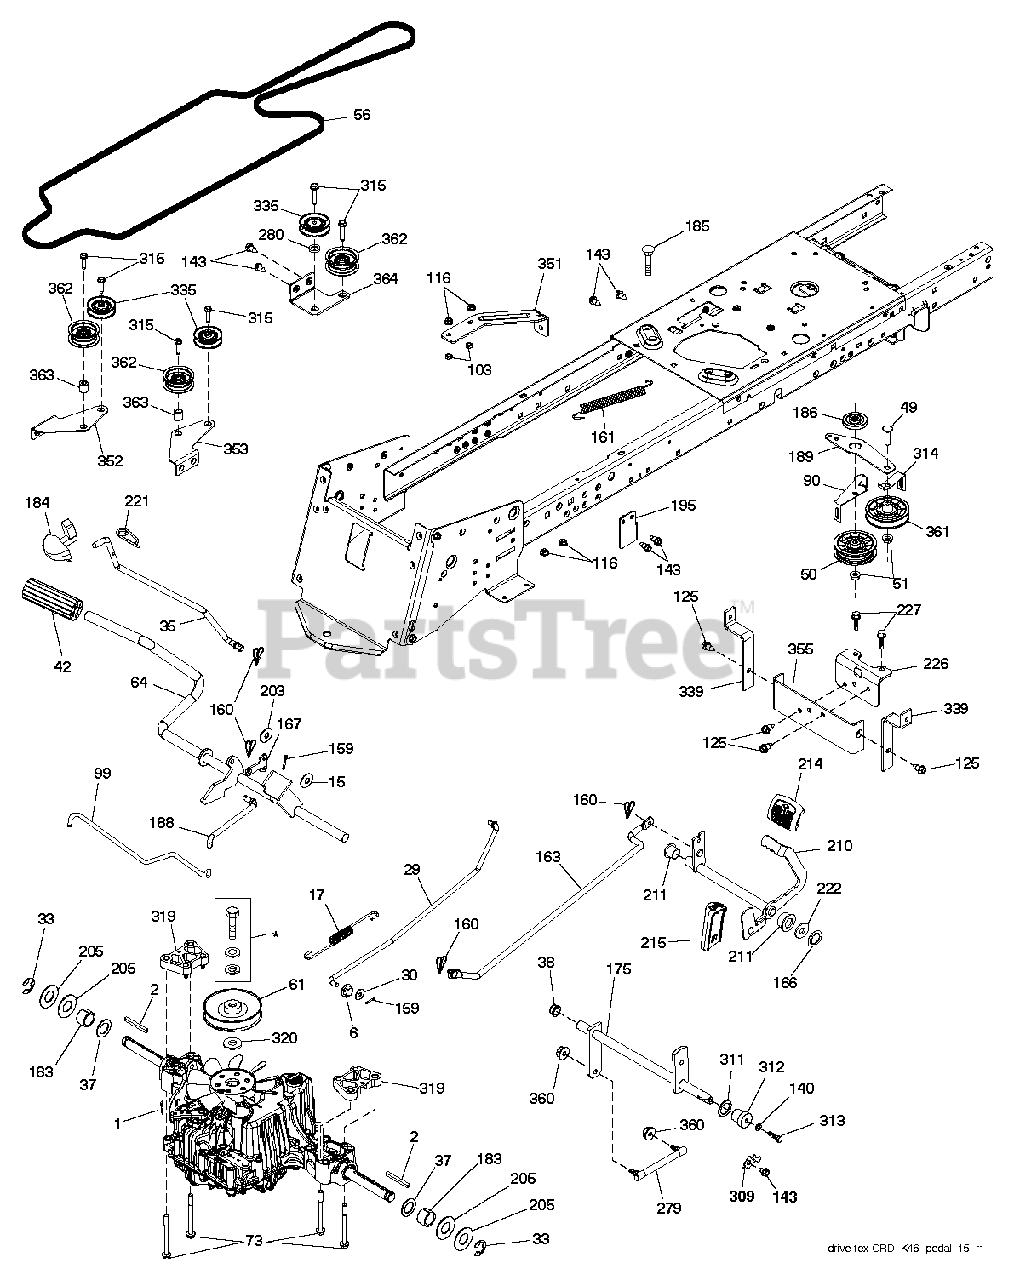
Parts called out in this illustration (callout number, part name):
2	SQUARE KEY
6	GROMMET T
33	E-RING LT
35	ROD.BRAKE.PARKING.LT.T
38	NYLINER SNAP 5/8" ID
42	PEDAL COVER T
49	BOLT
50	IDLER.FLAT.910.OFFSET
51	NUT LOCK FLG 3/8-16 UNC
64	SHAFT.ASM.PEDAL.BRK.CNTR
103	JAM NUT TI
116	NUT LOCK HEX FLANGE 5/16-18
125	SCREW
140	LOCKWASHER
159	COTTER PIN
160	RETAINER CLIP
161	SPRING, RETURN LT
166	NUT.PUSH.625
167	LATCH.BRAKE.SPRING
183	SPACER AXLE
184	HANDLE.PARKING.BRAKE.LTTEX.667
186	SPACER.RETAINER
188	LINK.CLUTCH.GROUND.DRIVE
203	WASHER
210	ROCKER.ASM.PEDAL.CONTR
211	BEARING.NYLON
214	PAD PEDAL FORWARD
221	RETAINER.SPRING.CLIP.H
222	WASHER 21/32 X 1-1/4 X 10 GA.
226	BRACKET.MOUNT.TORQUE.K46.TLT
227	SCREW
309	PLATE.FASTENING.CROSS.SHAFT
311	WASHER NYL
315	BOLT.5/16-18X1.25
320	WASHER.SPACER.MANDREL
335	PULLEY.V-IDLER.
361	IDLER.V-GROOVE.910.OFFSET
